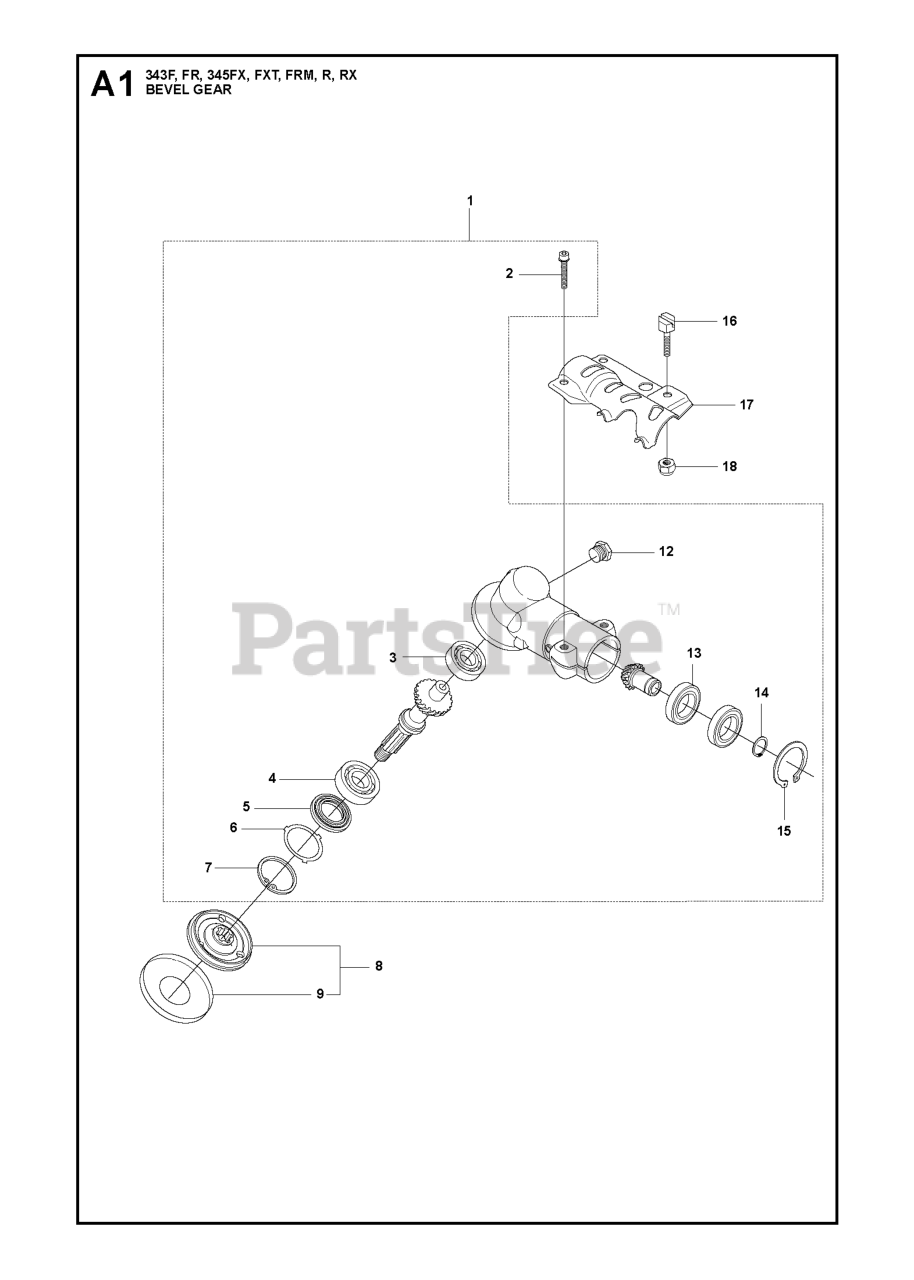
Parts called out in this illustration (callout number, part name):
1	GEAR ASSY
3	BALL BEARING
4	BALL BEARING
7	RETAINING RING SGH 35
8	RP CARRIER
9	RP TUBE INSERT
13	BALL BEARING
14	RETAINING RING SGA 15
15	RETAINING RING
17	BRACKET
18	LOCKNUT M6
